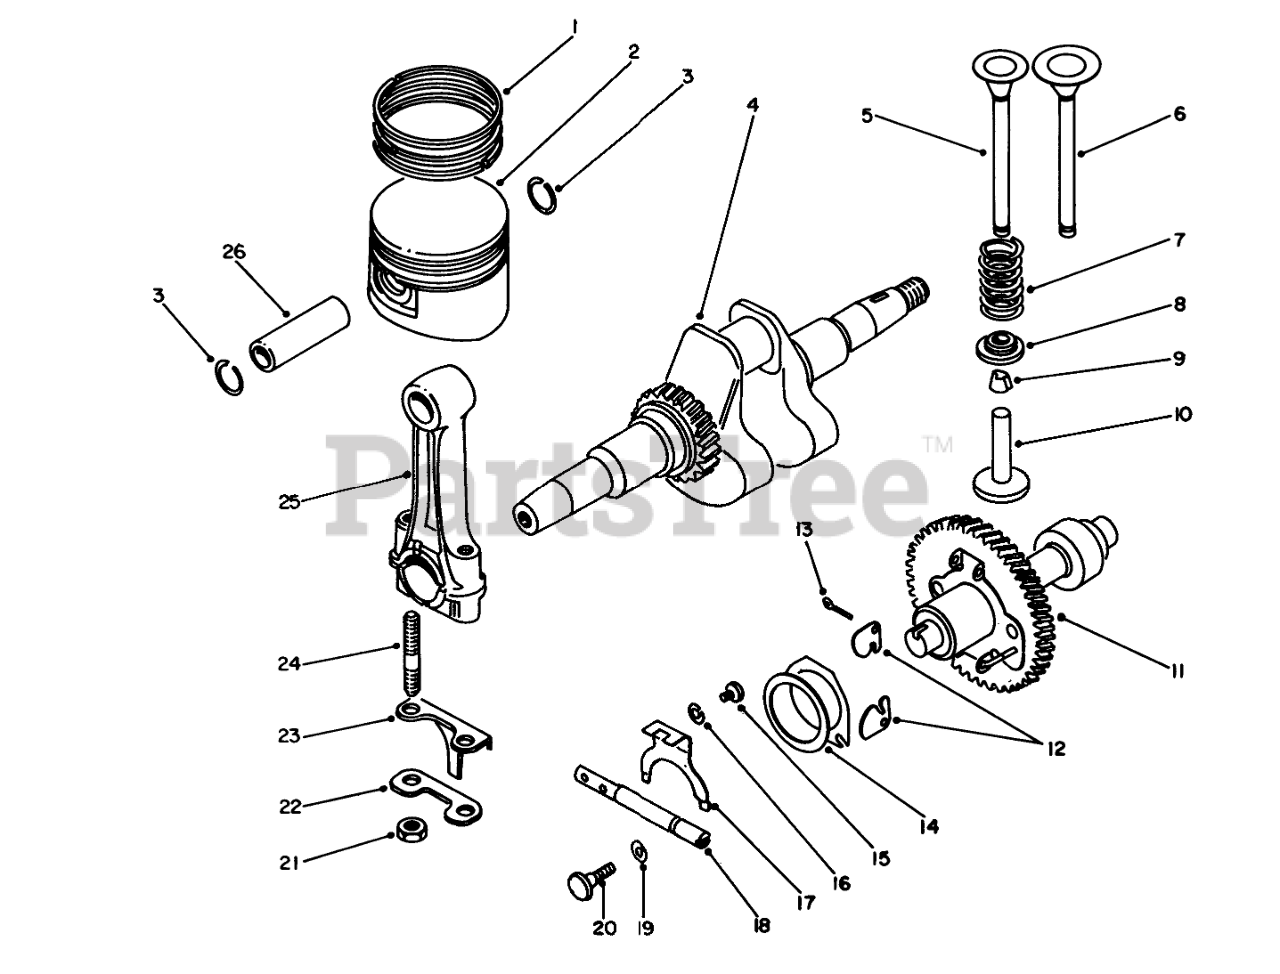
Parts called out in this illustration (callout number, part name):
1	Ring Set
2	Piston
3	Circlip
4	Crankshaft
5	EXHAUST VALVE
6	Valve-Intake
7	Spring
8	Retainer
9	Cotter
10	Tappet
11	Camshaft
13	Cotter Pin
14	Spacer
15	Screw
16	Lockwasher
17	PLATE
18	Shaft
19	Gasket
20	Screw
21	Nut
22	LOCK PLATE
23	Plate-Splash
25	Connecting Rod (Incl. Ref. #21-24)
26	PISTON PIN
